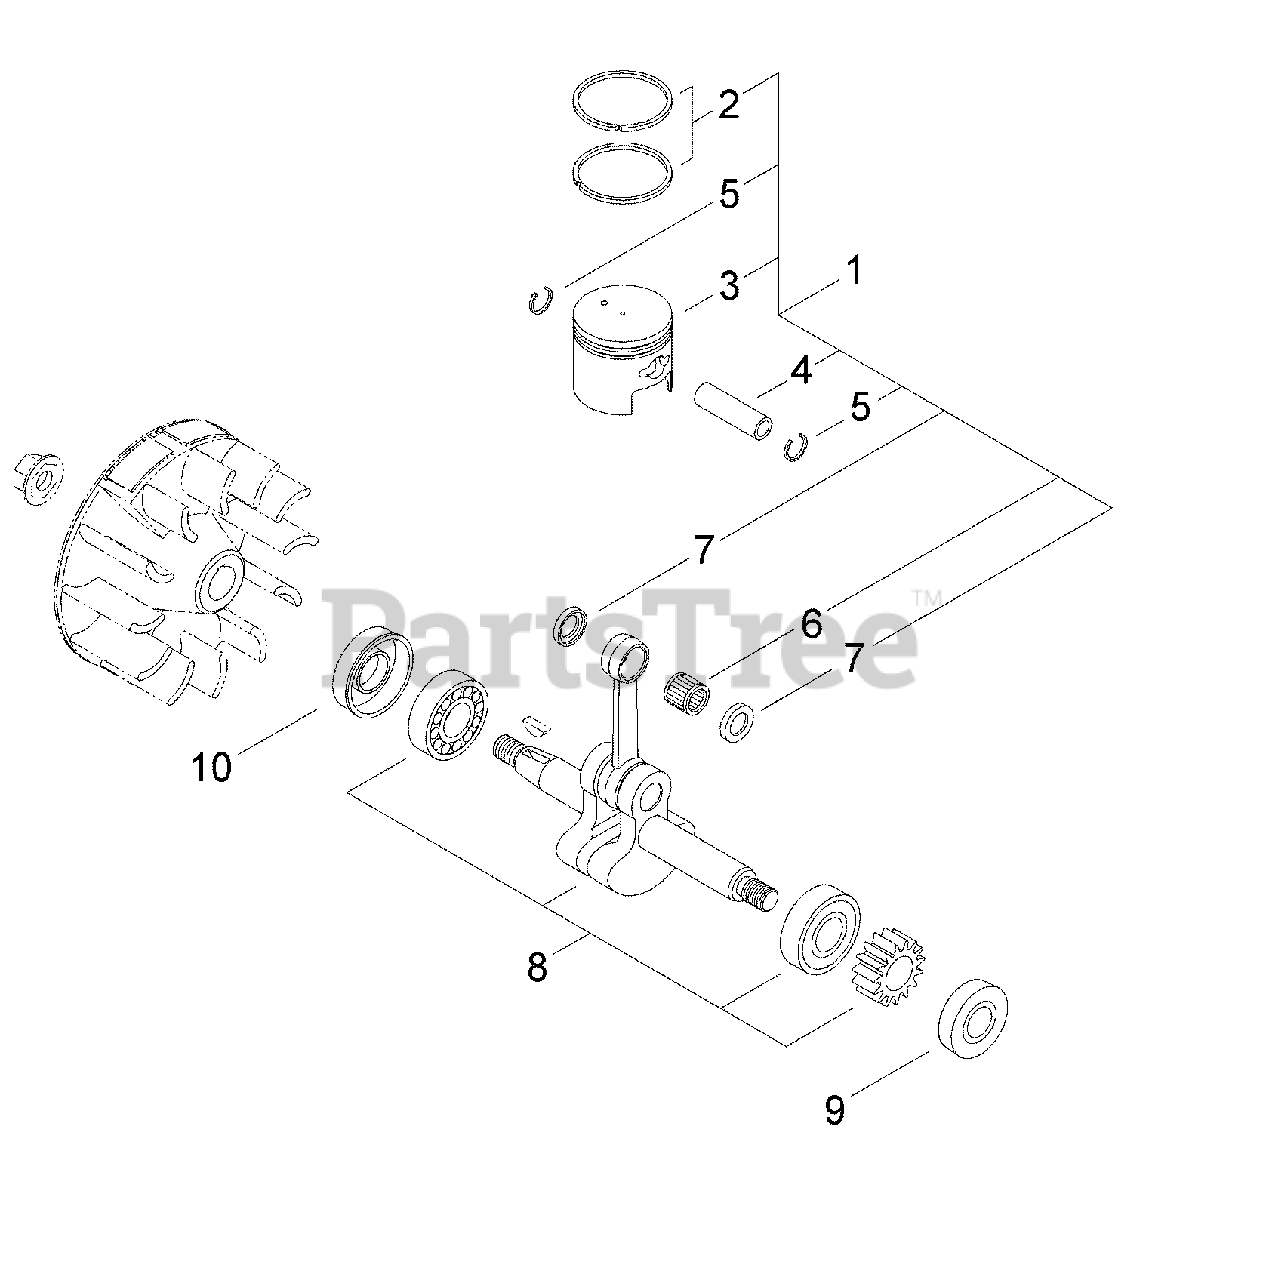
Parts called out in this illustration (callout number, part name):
1	PISTON KIT
2	RING, PISTON
3	PISTON
4	PIN, PISTON
5	RING, RETAINING
6	BEARING, NEEDLE
7	SPACER - 9
8	CRANKSHAFT ASSY
9	SEAL, OIL - 12
10	SEAL, OIL - 12
